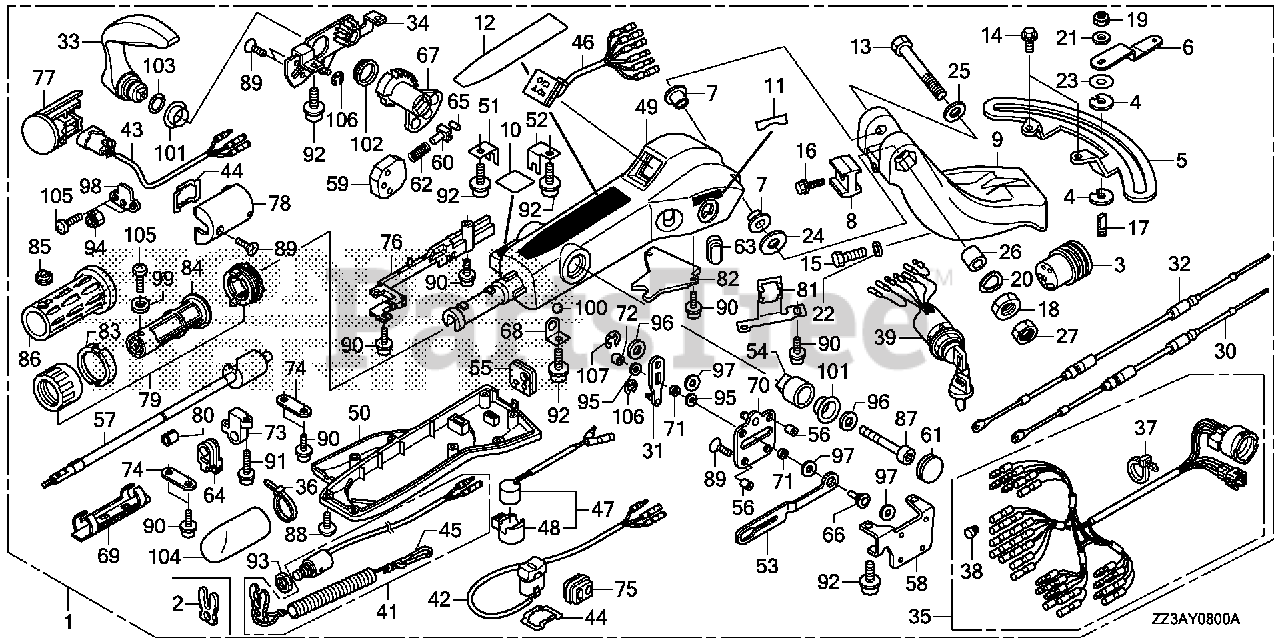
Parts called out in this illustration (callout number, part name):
1	HANDLEBAR KIT *NHB14M* (AQUA MARINE SILVER METALLIC)
2	CLIP, EMERGENCY LOCK
3	GROMMET, HANDLEBAR CABLE
4	BLOCK, FRICTION
5	PLATE, FRICTION
6	LEVER, FRICTION
7	BUSH, HANDLEBAR
8	BLOCK, HEIGHT ADJUSTER
9	BRACKET, STEERING *NHB14M* (AQUA MARINE SILVER METALLIC)
10	MARK, EMERGENCY SWITCH INDICATION (EU)
11	MARK, START
12	MARK, HANDLEBAR
13	BOLT, HEX. (12X80)
14	BOLT, FLANGE (6X12)
15	BOLT, HEX. (10X32)
16	BOLT, FLANGE (8X28)
17	BOLT, STUD (8X26)
18	NUT, HEX. (12MM)
19	NUT, SELF-LOCK (8MM)
20	WASHER, WAVE (14MM)
21	WASHER (8MM)
22	WASHER (10MM)
23	WASHER, NYLON (8MM)
24	WASHER, PLAIN (12MM)
25	WASHER, PLAIN (12MM)
26	COLLAR, DISTANCE (12.2X23X16)
27	NUT, HEX. (12MM)
30	CABLE, THROTTLE
31	ARM ASSY., THROTTLE
32	CABLE, SHIFT
33	LEVER, SHIFT
34	FRAME ASSY., SHIFT
35	CABLE ASSY. A, LONG HANDLE
36	BAND (CONVEX CV-150)
37	BAND (CONVEX CV-200)
38	PLUG, CONNECTOR (INNER)
39	SWITCH ASSY., COMBINATION
41	SWITCH ASSY., EMERGENCY STOP
42	SWITCH ASSY., TROLLING CONTROL
43	SWITCH ASSY., POWER TILT
44	PLATE, SWITCH
45	WIRE, EMERGENCY
46	LAMP ASSY., INDICATOR
47	BUZZER ASSY., WARNING
48	SUSPENSION, WARNING BUZZER
49	HOUSING *NHB14M* (AQUA MARINE SILVER METALLIC)
50	COVER (LOWER)
51	CLAMP, SHIFT CABLE
52	CLAMP, THROTTLE CABLE
53	PLATE, LOCK
54	STOPPER, SHIFT
55	GROMMET
56	SPACER
57	SHAFT ASSY., THROTTLE
58	FRAME, THROTTLE
59	GUIDE, SPRING
60	ACTUATOR
61	CAP
62	SPRING
63	GROMMET, POWER TILT SWITCH
64	GROMMET, POWER TILT SWITCH
65	ROLLER
66	PIN, SLIDE
67	GEAR, SHIFT
68	PLATE, BALL GUIDE
69	GUIDE, THROTTLE HARNESS
70	FRAME ASSY., THROTTLE SUB
71	ROLLER, PLATE
72	ROLLER, CAM
73	STAY
74	PLATE, SHIFT CLAMP
75	GROMMET, SIDE
76	GUIDE, HARNESS
77	BOX ASSY., POWER TILT SWITCH (1)
78	BOX ASSY., POWER TILT SWITCH (2)
79	GRIP ASSY., THROTTLE FRICTION
80	BUSH, THROTTLE SHAFT
81	HOLDER, SWITCH
82	PLATE, HARNESS
83	PAD, THROTTLE FRICTION
84	PIPE, THROTTLE GRIP
85	CAP, GRIP
86	RUBBER, GRIP
87	BOLT, SOCKET (8X70)
88	BOLT (M5X12)
89	SCREW, FLAT (5X14)
90	BOLT (5X12)
91	BOLT (5X20)
92	BOLT (6X15)
93	NUT, HEX. (16MM)
94	NUT, NYLON (5MM)
95	WASHER
96	WASHER (8MM)
97	WASHER
98	WASHER, PLATE
99	WASHER (5MM)
100	BALL, STEEL
101	BEARING
102	BEARING
103	O-RING (20.6X1.9)
104	TUBE, CORD (30MM)
105	SCREW, PAN (5X14)
106	E-RING (4MM)
107	E-RING (7MM)
